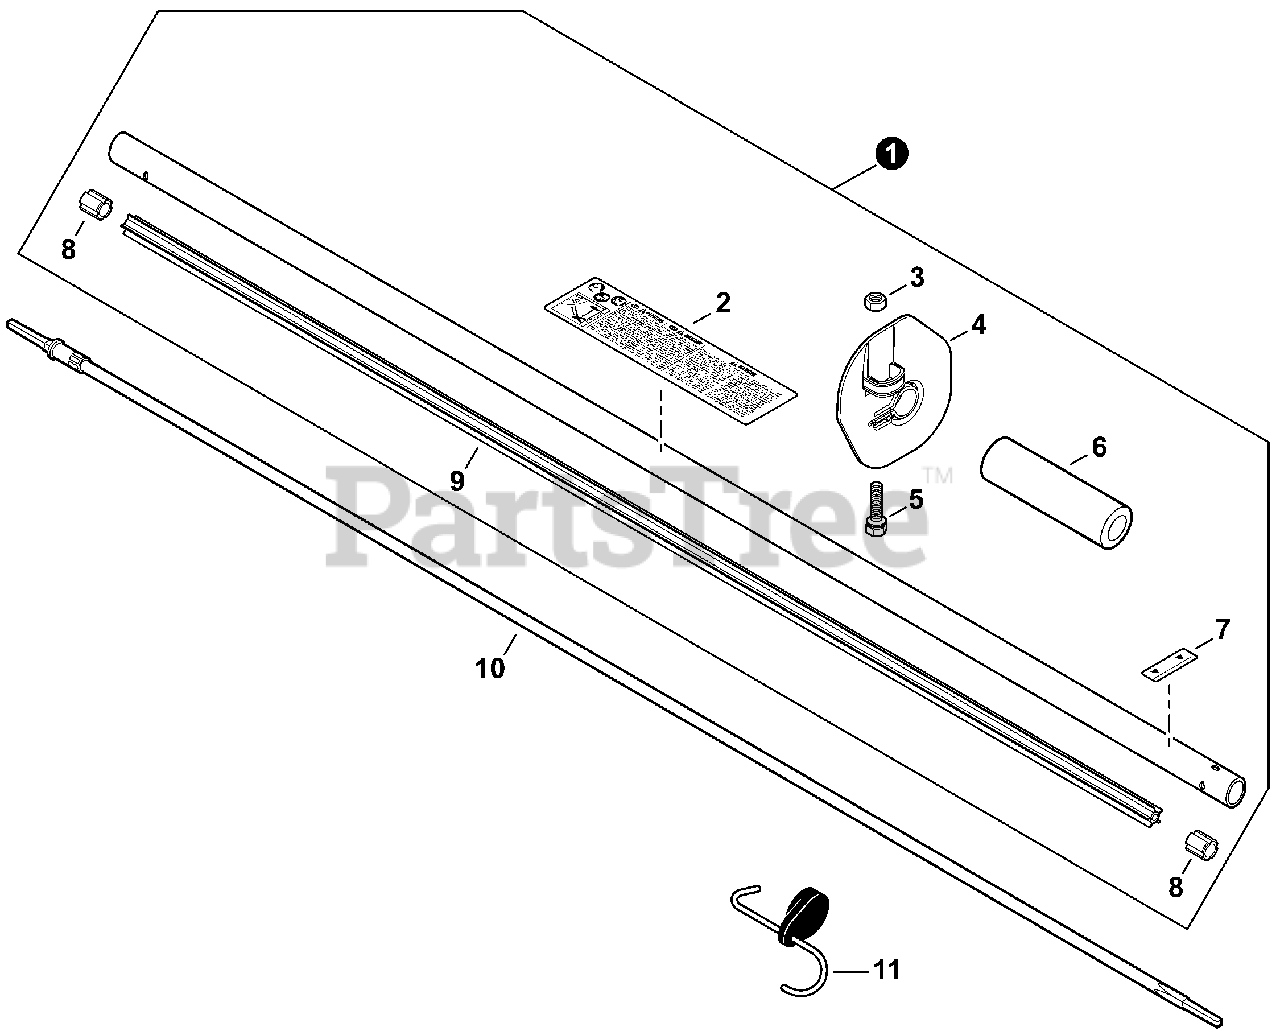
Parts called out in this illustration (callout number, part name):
1	MAIN PIPE ASSY
2	LABEL, CAUTION
3	NUT M5
4	GUARD, HAND
5	BOLT 5×20
6	GRIP, HANDLE
7	LABEL - ALIGNMENT
9	LINER - FLEXIBLE
10	DRIVESHAFT - FLEXIBLE
11	HANGER, ATTACHMENT
